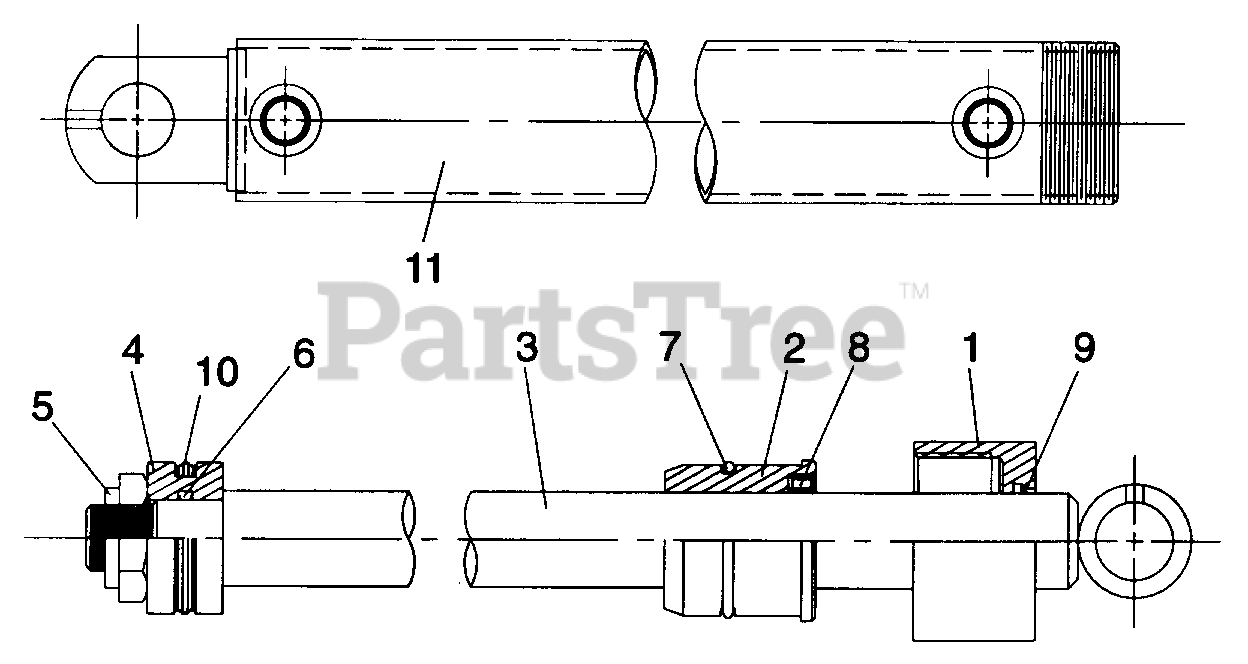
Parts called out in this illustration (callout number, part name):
1	Retainer nut
2	Seal retainer
4	Piston
5	Locknut
10	Piston seal
